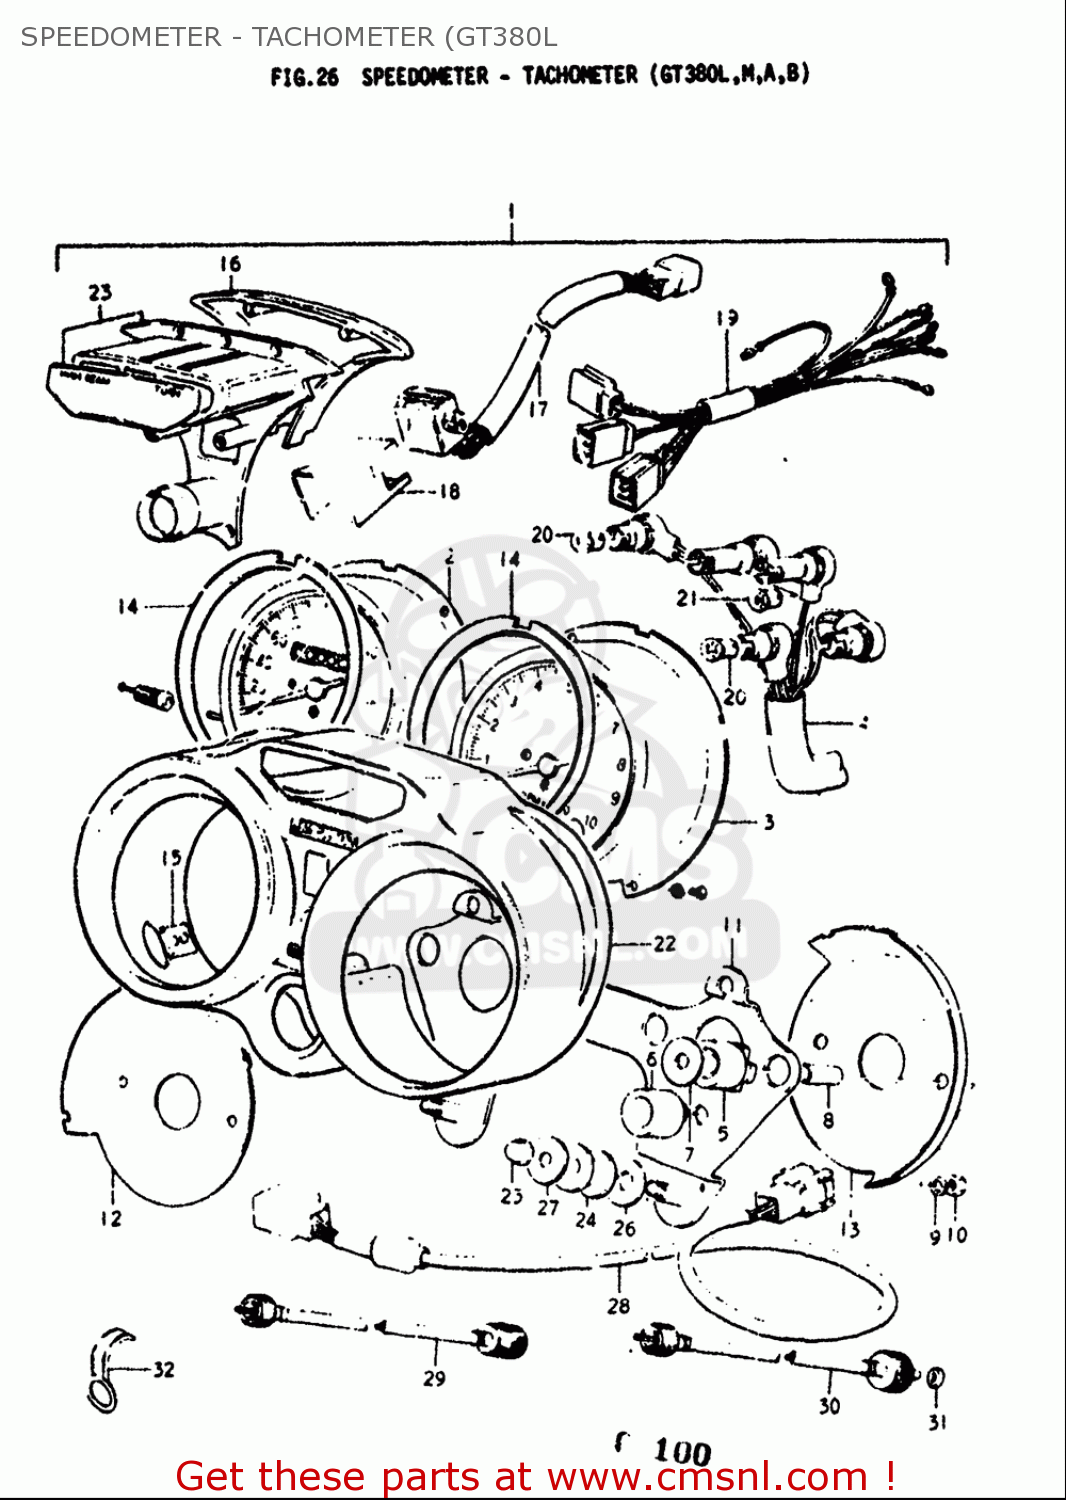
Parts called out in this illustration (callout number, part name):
5	CUSHION,METER NO.1
6	CUSHION,METER
7	WASHER(5.5X16X1.5)
9	WASHER,LOCK
10	NUT
15	CAP
20	BULB(12V3.4W,STANLEY,A72A)
21	BULB(12V1.7W,A71A)
24	CUSHION
25	NUT
26	WASHER(6.5X18X1.6)
27	WASHER
29	CABLE ASSY,SPEEDOMETER
30	CABLE ASSY,TACHOMETER
31	SEAL,OIL SPEEDOMETER CABLE
32	LAMP ASSEMBLY
